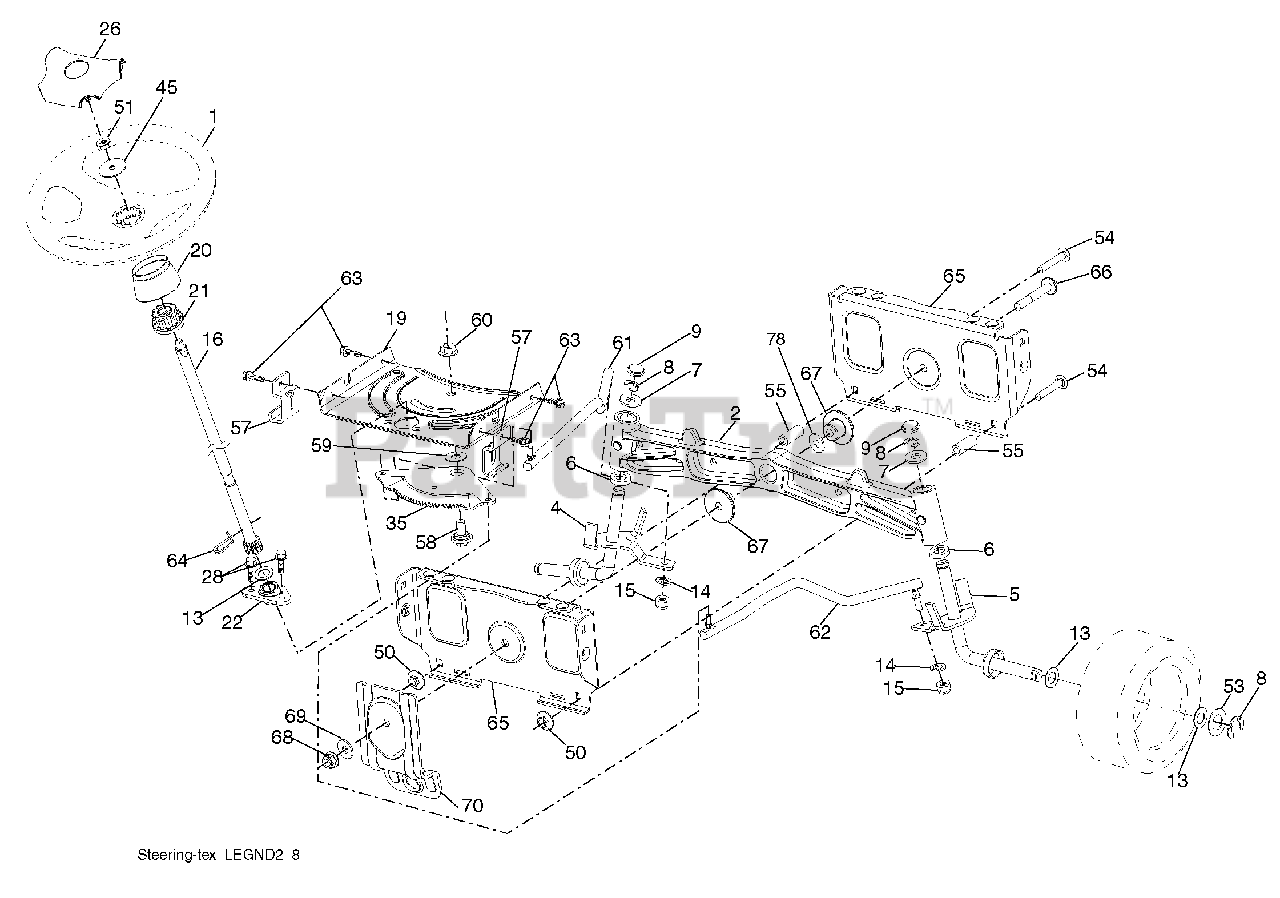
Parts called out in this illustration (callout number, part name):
1	Wheel, Steering
2	Axle Asm., Front
4	Spindle Asm., LH
5	Spindle Asm., RH
6	Bearing, Race Thrust Harden
7	Washer 25/32 x 1-5/8 x 16 Ga.
8	Ring, Clip #T5304-75
9	Cap, Spindle
13	Washer 25/32 x 1-1/4 x 16 Ga.
14	Washer, Lock Hvy. Hlcl. Spr. 3/8
15	Nut, Crown Lock 3/8-24 unf
16	Shaft Steering
19	Plate Steering
20	Boot, Steering
21	Adapter, Wheel Steering
22	Bushing, Strg. Blk.
26	Insert, Wheel Steering
28	Screw 3/8-16 x 3/4
35	Gear, Sector Plate
45	Washer 11/32 x 2-3/8 x 12 Ga.
50	Nut Lock 3/8-16 unc
51	Nut Hex Jam Toplock 1/2-20 unf
53	Washer Hardened .793 x 1.637 x .060
54	Bolt Hex 3/8-16 unc x 2-1/4
55	Spacer Brace Axle
57	Bracket Upstop
58	Bolt Shoulder Sector Pivot CFM
59	Washer Thrust Sector Steering
60	Nut Flange Lock 5/8-11
61	Draglink LH
62	Draglink, RH
63	Screw 5/16-18 x 3/4
64	Retainer Clip Spring Steering
65	Brace Axle Front
66	Bolt Hex Fghd. 7/16-14 x 3 Serr.
67	Bushing PM Front Axle
68	Nut Lock Flange 7/16-14 Gr. 5
69	Washer 1.5 x .505 x .118
70	Bracket Deck Susp. Front
78	Washer Thrust
